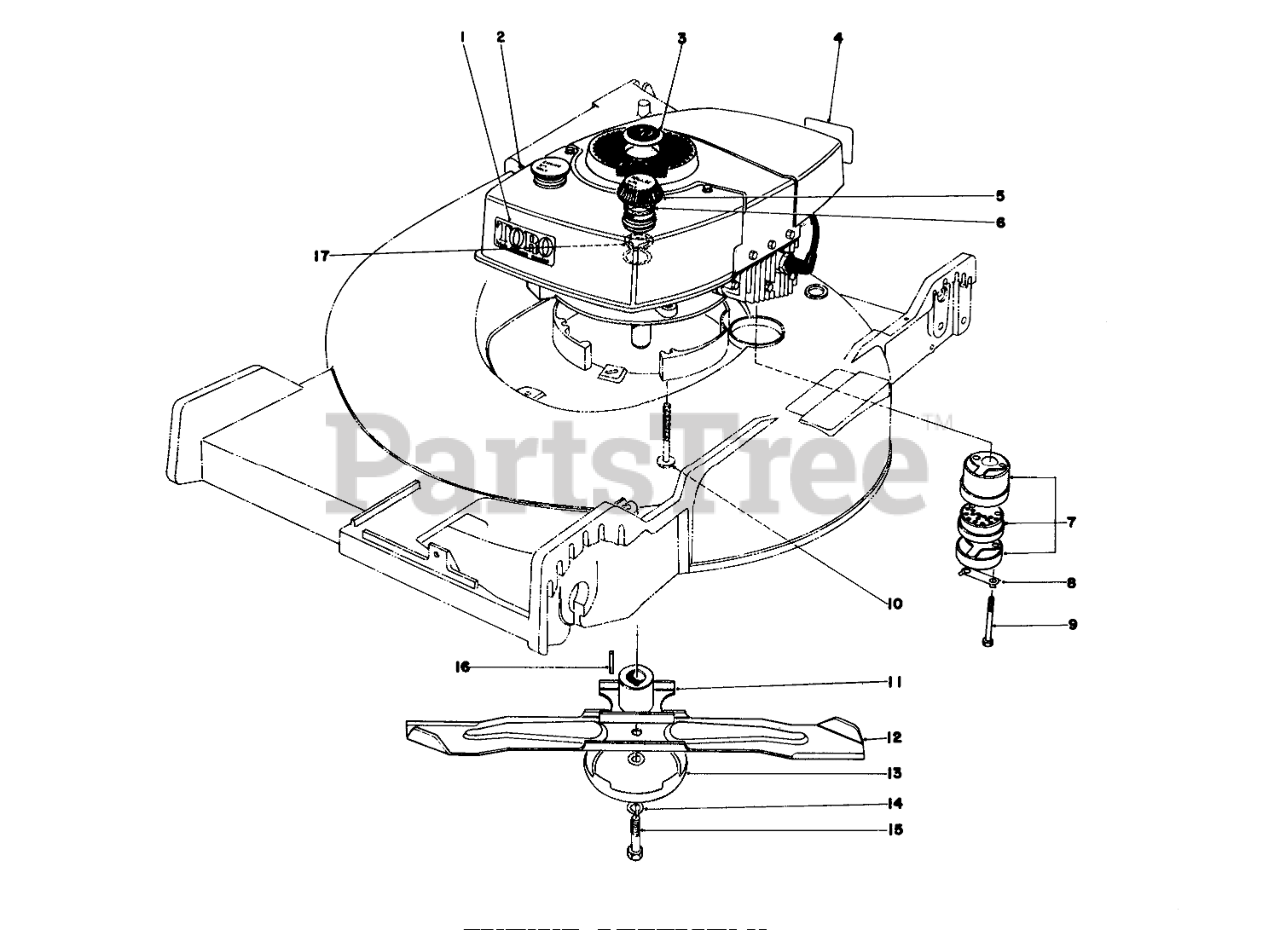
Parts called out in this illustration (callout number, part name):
1	High Torque
2	Engine
3	PLUG BUTTON
4	Decal Maintenance
5	Gas Cap (Incl. Ref. #6 & 17)
6	GASKET
7	Muffler Assembly (Incl. Ref. #8 & 9)
8	CLIP - LOCKING
9	SCREW-HH
10	3/8-16 X 2-3/4 CAPSCR
11	Blade Retainer
12	Blade
13	AntiScalp Cup
14	WASHER-LOCK
15	SCREW-BLADE
16	SQUARE KEY
17	GAS CAP BAFFLE
